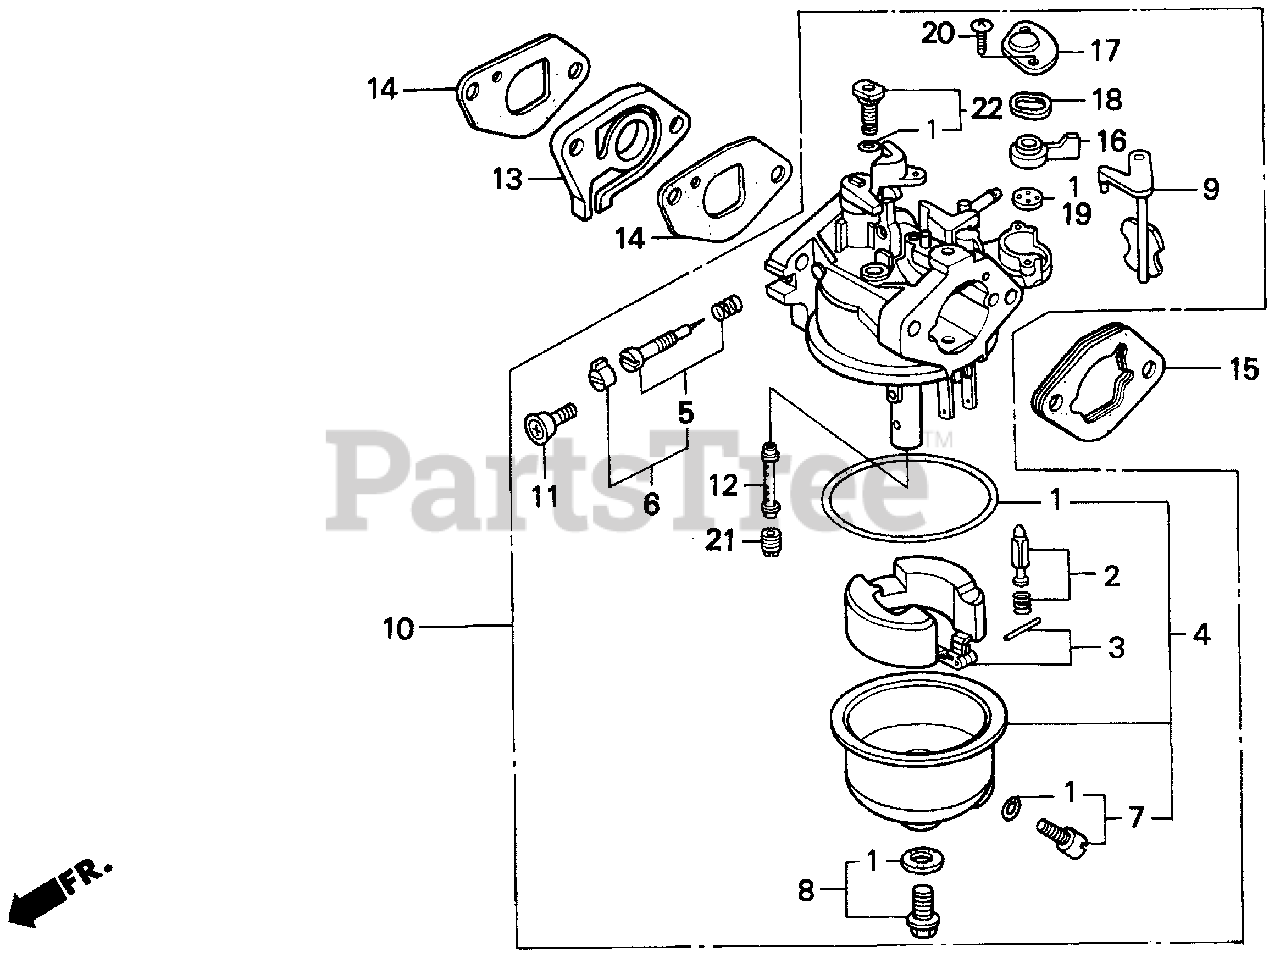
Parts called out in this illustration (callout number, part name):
1	GASKET SET
2	VALVE SET, FLOAT
3	FLOAT SET
4	CHAMBER SET, FLOAT
5	SCREW SET, PILOT
7	SCREW SET, DRAIN
8	SCREW SET B
9	CHOKE SET
10	CARBURETOR ASSY. (BE03A H)
11	SCREW, THROTTLE STOP
12	NOZZLE, MAIN
13	INSULATOR, CARBURETOR
14	GASKET, INSULATOR (NOT AVAILABLE)
14	GASKET, INSULATOR
15	SPACER, CARBURETOR
16	LEVER, VALVE
17	PLATE, LEVER SETTING
18	SPRING, VALVE LEVER
19	GASKET, VALVE
20	SCREW, PAN (3X8)
21	JET, MAIN (#60)
21	JET, MAIN (#62)
21	JET, MAIN (#65)
22	JET SET, PILOT (#35)
